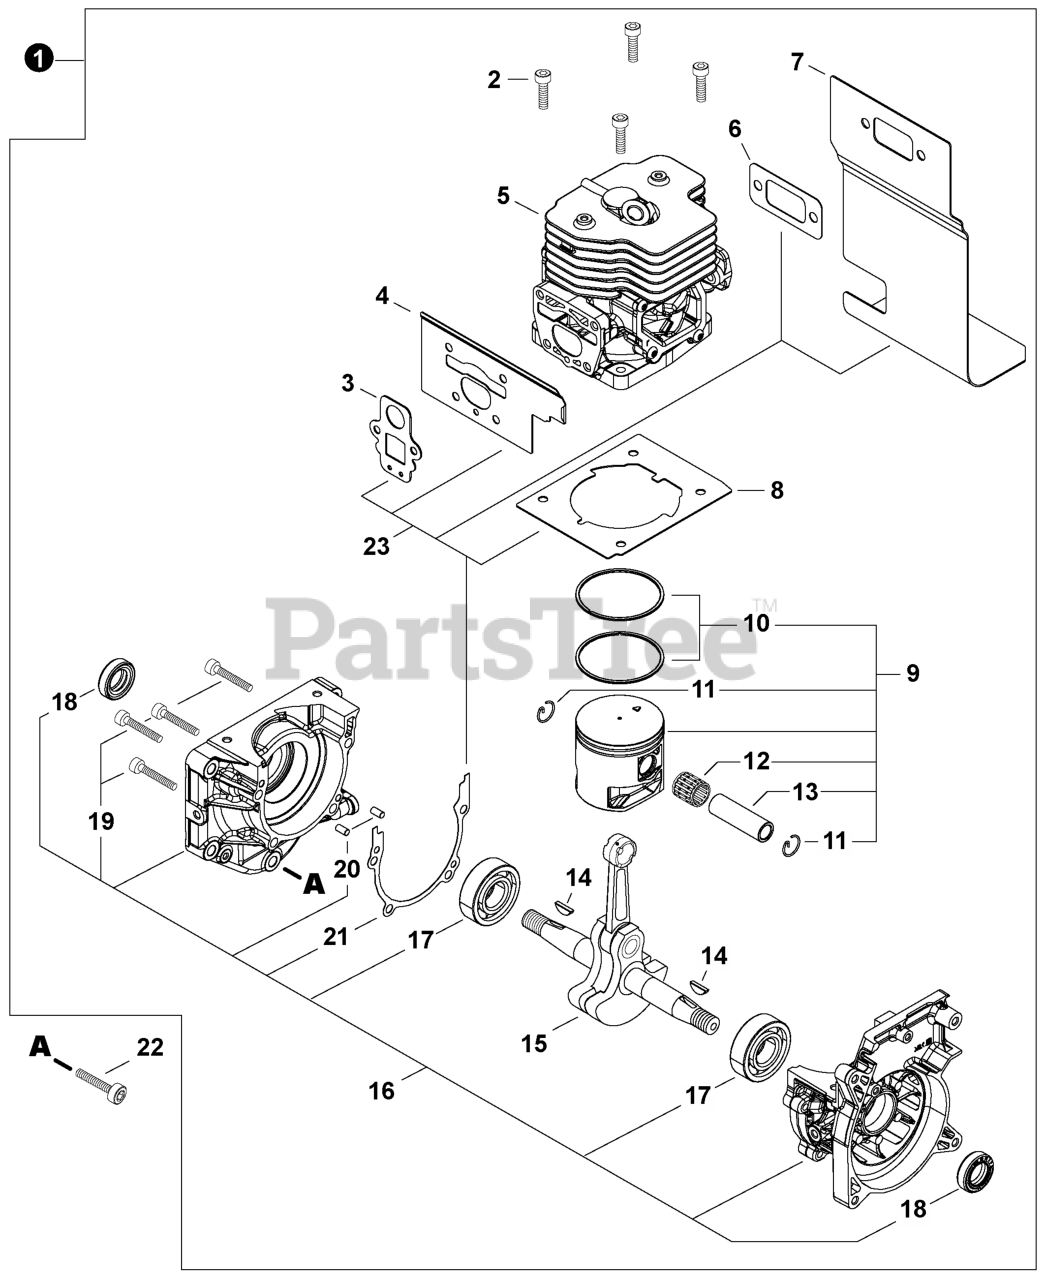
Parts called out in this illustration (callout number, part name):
1	SHORT BLOCK
2	BOLT, TORX 5x25
3	GASKET, INTAKE
4	HEAT SHIELD, INTAKE
5	CYLINDER ASSY
6	GASKET, EXHAUST
7	HEAT SHIELD, EXHAUST
8	GASKET, CYLINDER
9	PISTON KIT
10	RING, PISTON
11	RING, RETAINING
12	BEARING, NEEDLE 13
13	PIN, PISTON
14	KEY, WOODRUFF 3x14
15	CRANKSHAFT ASSY
16	CRANKCASE SET
17	BEARING, BALL 6203
18	SEAL, OIL 15
19	BOLT, TORX 5x30
20	PIN, LOCATING 4x8
21	GASKET, CRANKCASE
22	BOLT, TORX 6x30
23	GASKET KIT: ENGINE, INTAKE, EXHAUST
